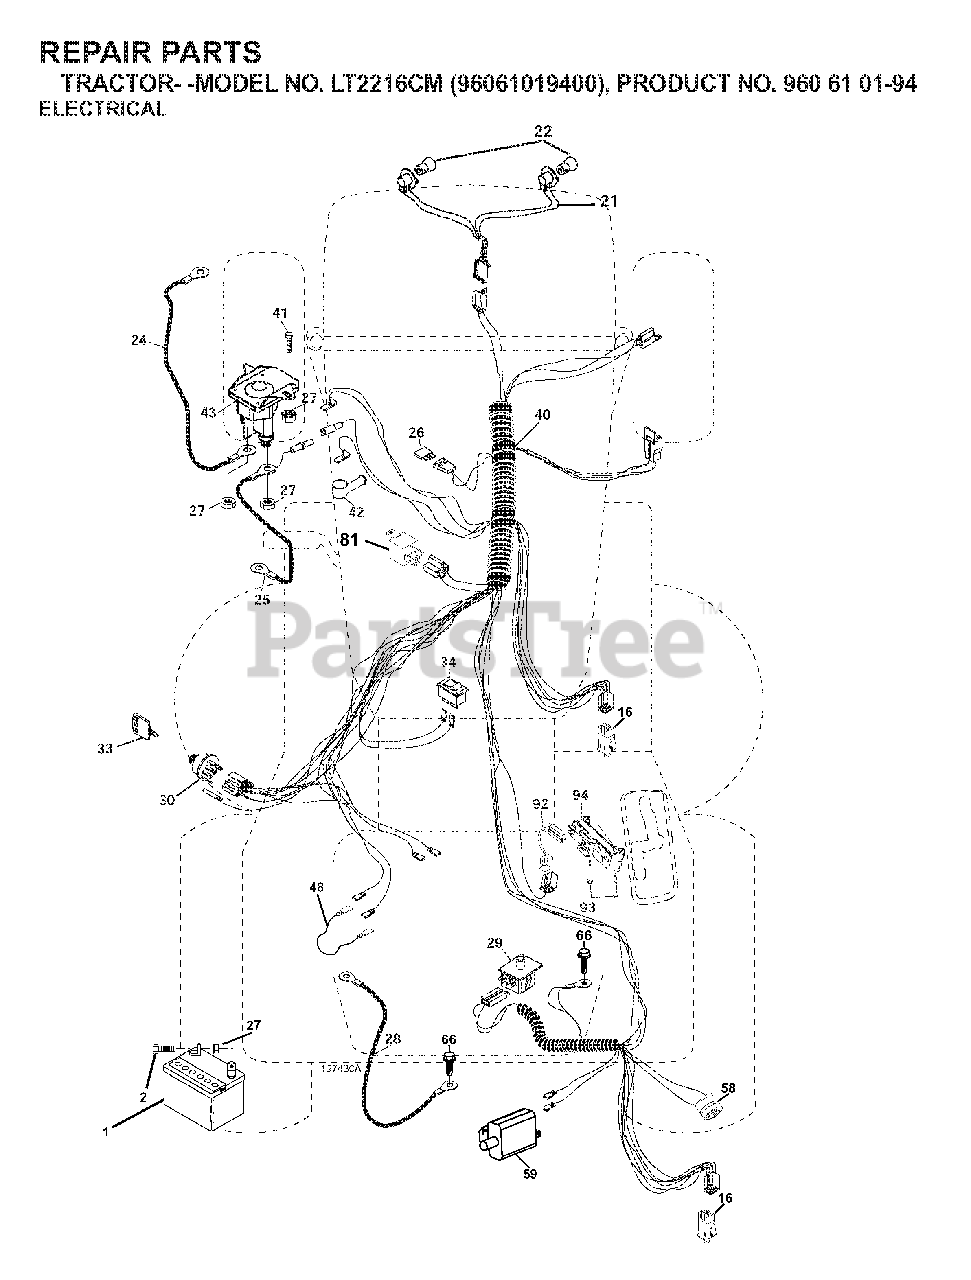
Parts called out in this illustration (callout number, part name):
1	REPL BY 532 12 38-99
16	SWITCH INTERLOOK PUSH-IN
21	HARNESS ASSY LIGHT
22	LIGHTBULB
24	BATTERY CABLE GT
25	CABLE BATTERY
26	FUSE 20AMP
27	NUT
28	CABLE GROUND
29	SWITCH.SEAT.DP W/RAMPS
30	SWITCH.IGN.DELTA.W.LGH.ROS
33	KEY MLD GEN DELTA
34	SWITCH LT
42	TERMINAL COVER
43	SOLENOID.W/BRASS.PLUNG
58	BUZZER
81	RELAY.ASSY.T
92	HARNESS.PIGTAIL.CONSLE
93	SCREW.PLASTITE
94	MODULE.REVERSE.ROS
